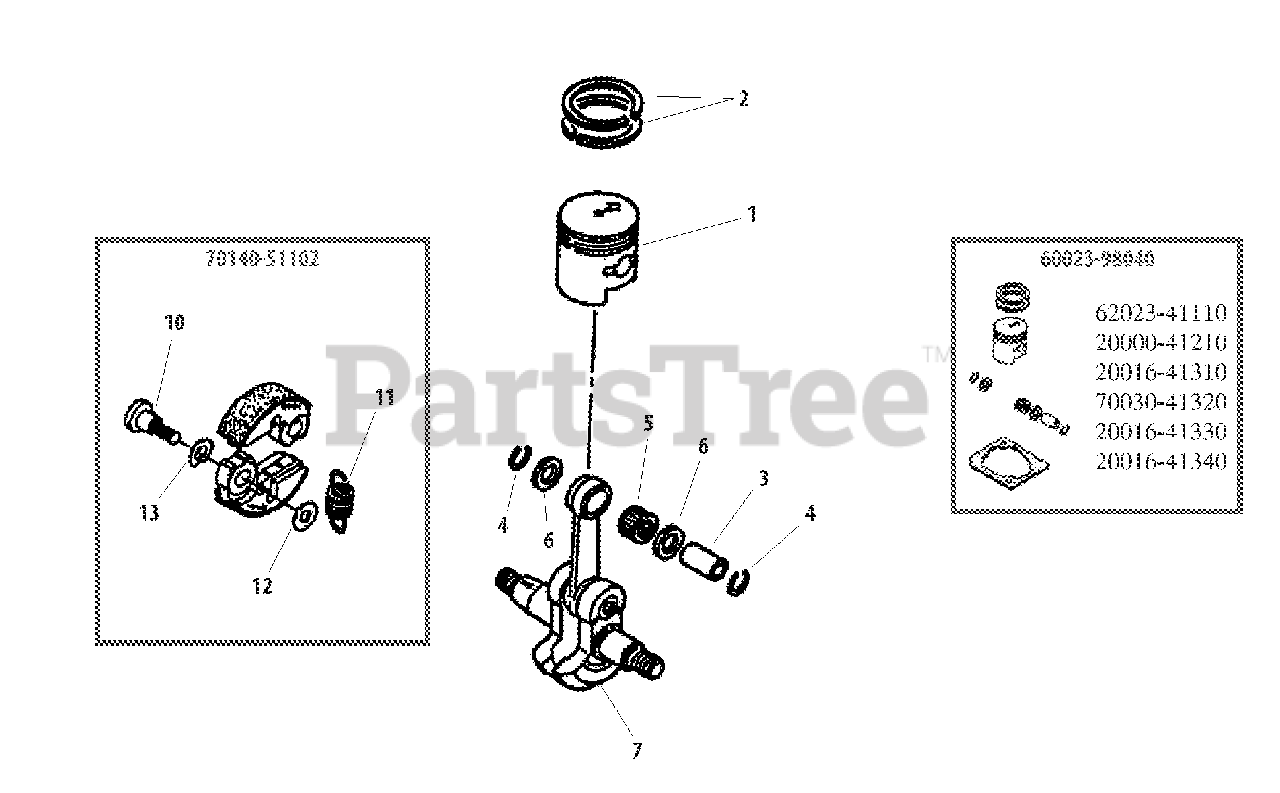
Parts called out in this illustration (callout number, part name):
1	PISTON
2	RING, PISTON
3	PIN, PISTON
4	RING, SNAP
5	BEARING, NEEDLE
6	WASHER, THRUST
7	CRANKSHAFT
10	BOLT, CLUTCH
11	SPRING
12	WASHER 6 MM
13	WASHER, SPRING
60023-98040	PISTON KIT
70140-51102	CLUTCH ASSY
